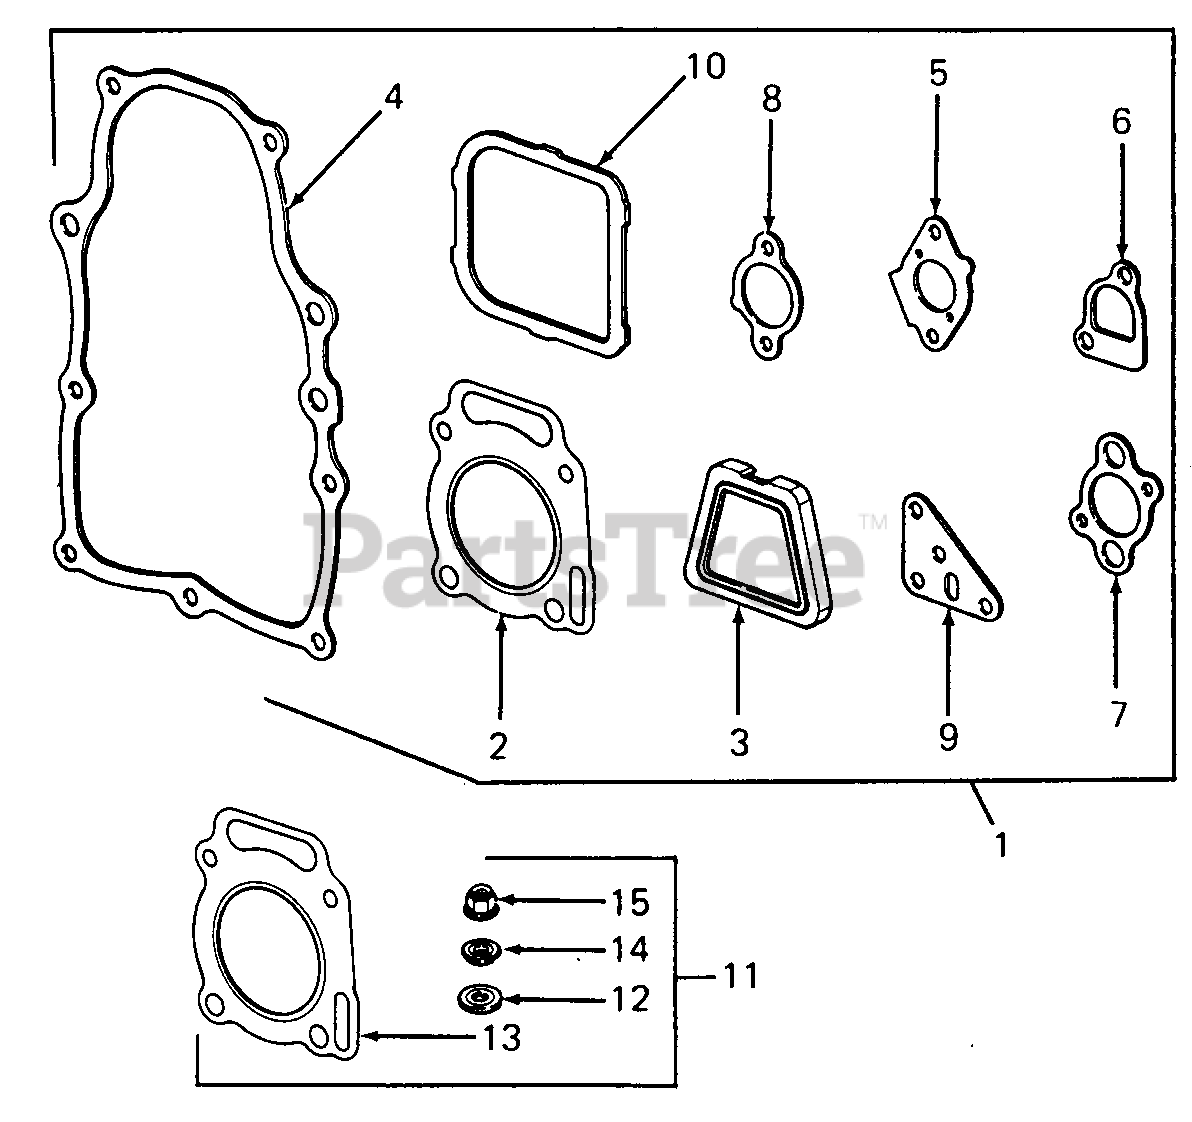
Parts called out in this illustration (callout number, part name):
1	Gasket Set
2	Gasket, Cylinder Head
3	Gasket, Breather
4	Gasket, Cover
5	Gasket, Carburetor Mtg
6	Gasket, Intake Manifold
7	Gasket, Air Cleaner
8	Gasket, Exhaust Manifold
9	Gasket, Adapter
10	Gasket, Valve Cover
11	Overhaul Kit, Valve
13	Gasket, Cylinder Head
14	Washer
15	Nut, Nylock
